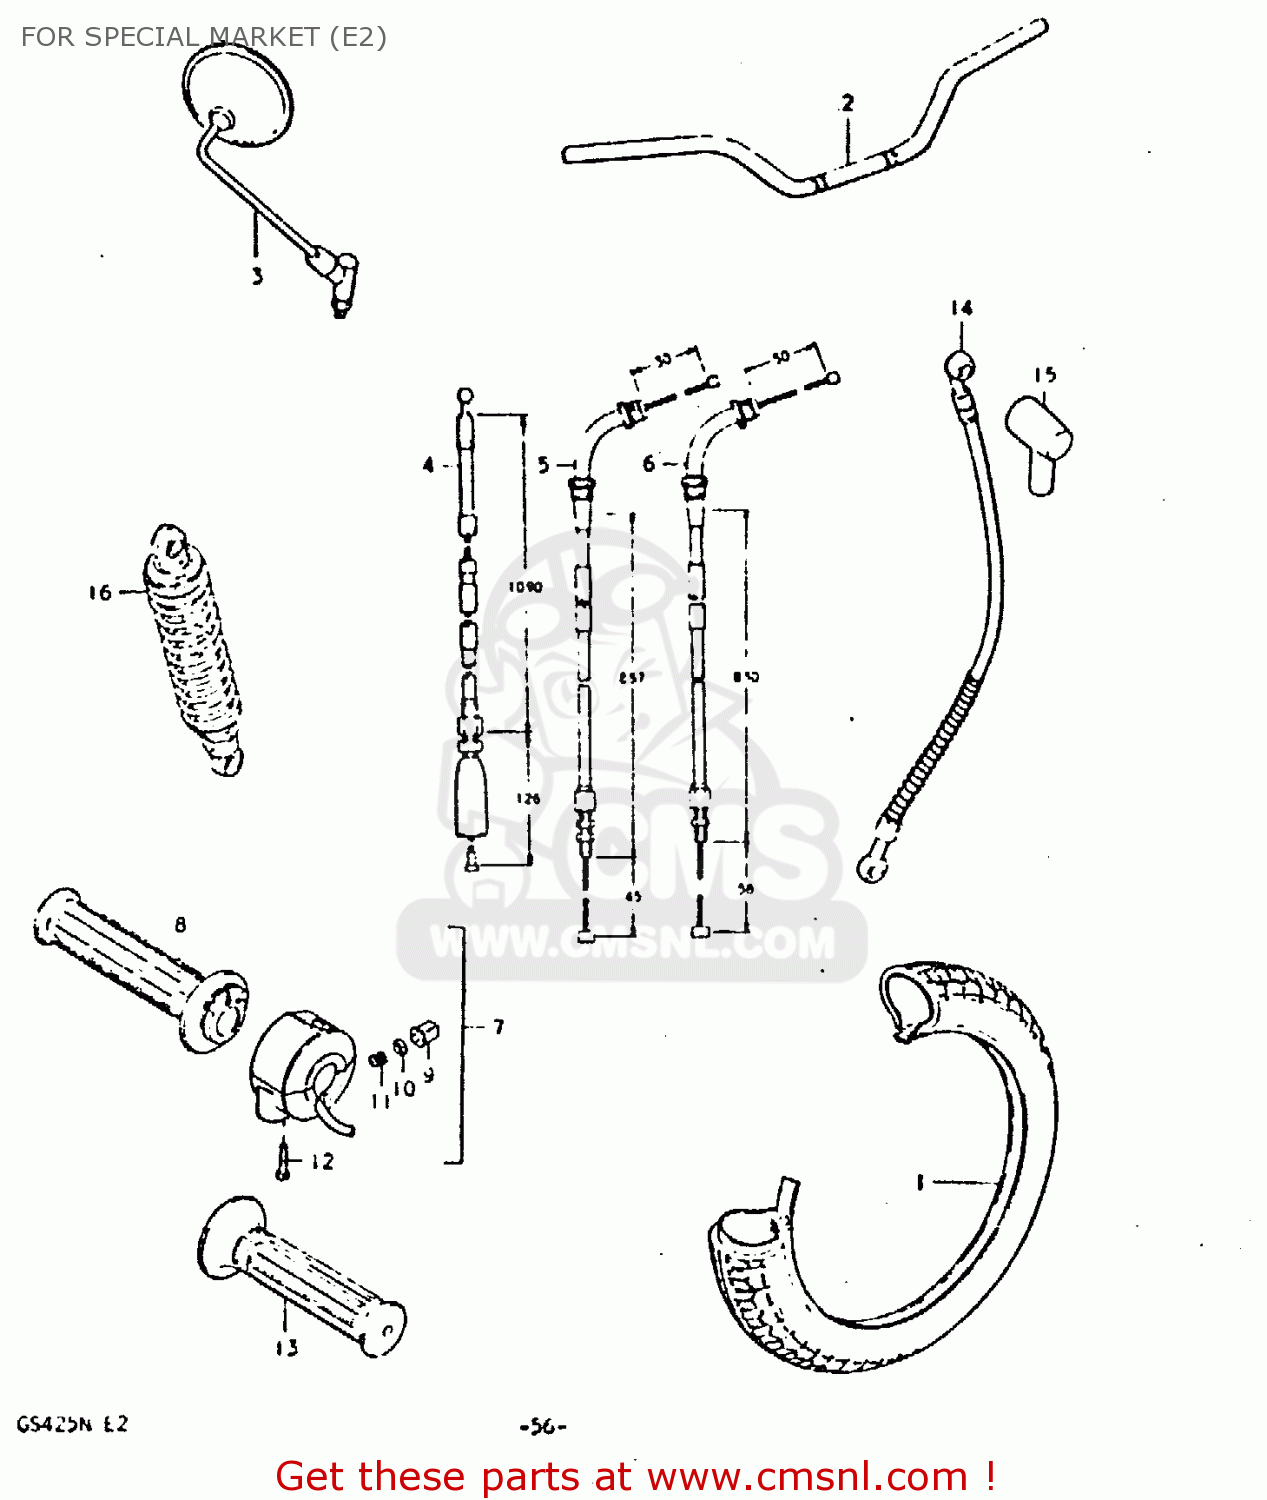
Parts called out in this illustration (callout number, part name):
1	TIRE (3.00S18) DUNLOP
2	HANDLEBAR
3	MIRROR ASSY,RH
4	CABLE ASSY, CLUTCH
5	CABLE ASSY, THROTTLE (1)
6	CABLE ASSY, THROTTLE (2)
7	CASE ASSEMBLY,THROTTLE
8	GRIP,THROTTLE
9	BUTTON,HORN
10	CONTACT
11	SPRING
12	SCREW
13	GRIP,L
14	HOSE,FRONT BRAKE
15	BOOT
16	SHOCK ABSORBER, REAR
